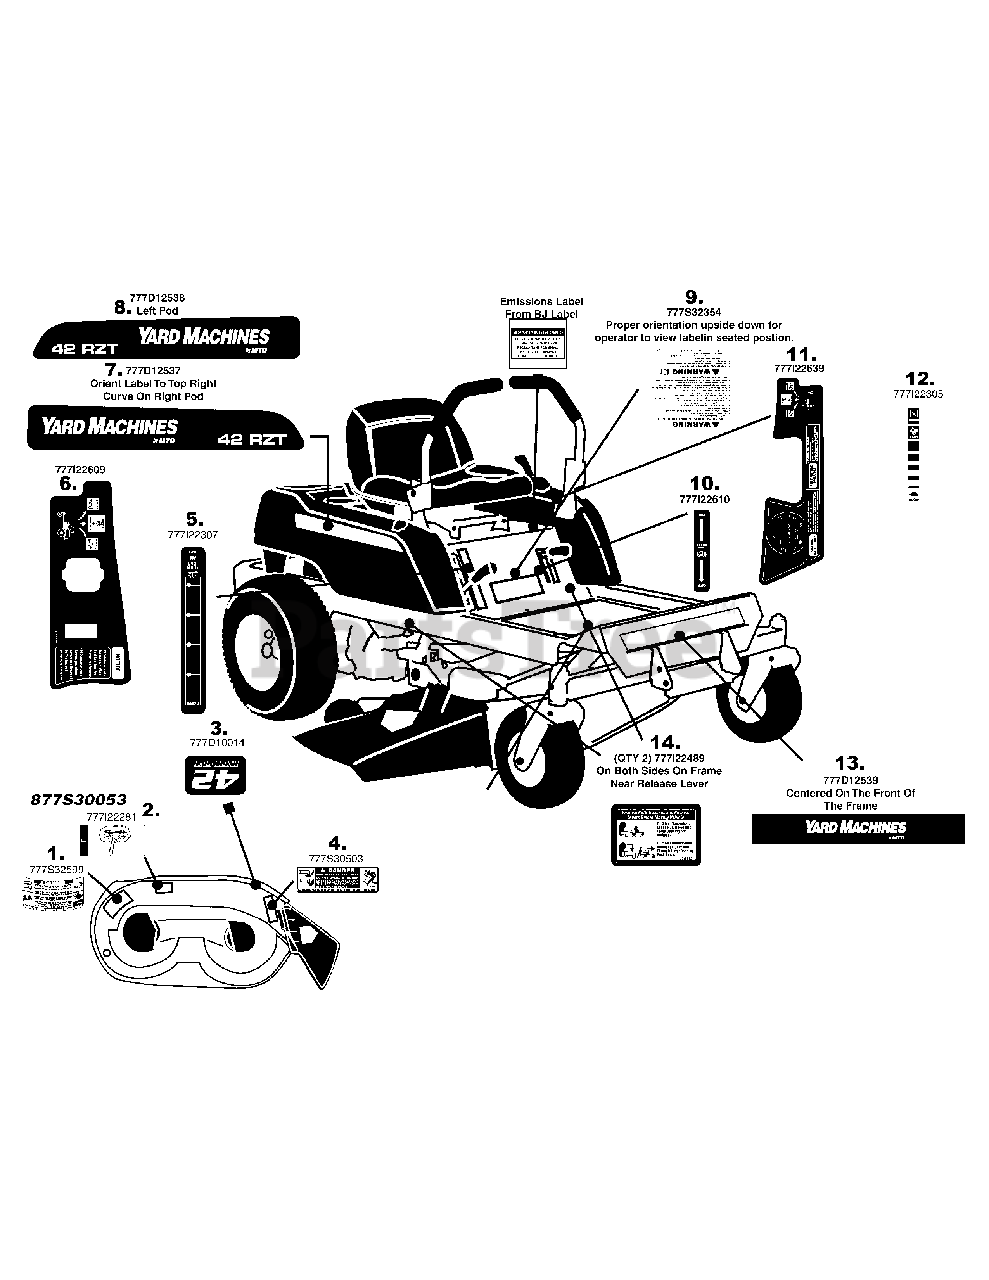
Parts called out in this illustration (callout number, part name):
1	LABEL-RZT DECK WARNG CURVE
2	LABEL-BELT ROUTE
3	LABEL-RZT DECK 42" CUT
4	LABEL-DANGER CHUTE
5	LABEL-HANDLE HEIGH
6	LABEL-RH CONTROL
7	LABEL-RZT YARD MACHINE POD RH
8	LABEL-RZT YARD MACHINE POD LH
9	LABLE-RDR SAFETY
10	LABEL-PARK BRAKE
11	LABEL-LH CONTROL
12	LABEL-THROTTLE
13	LABEL-RZT YARD MACHINE FRONT
14	LABEL-TRNMSN RELEASE
